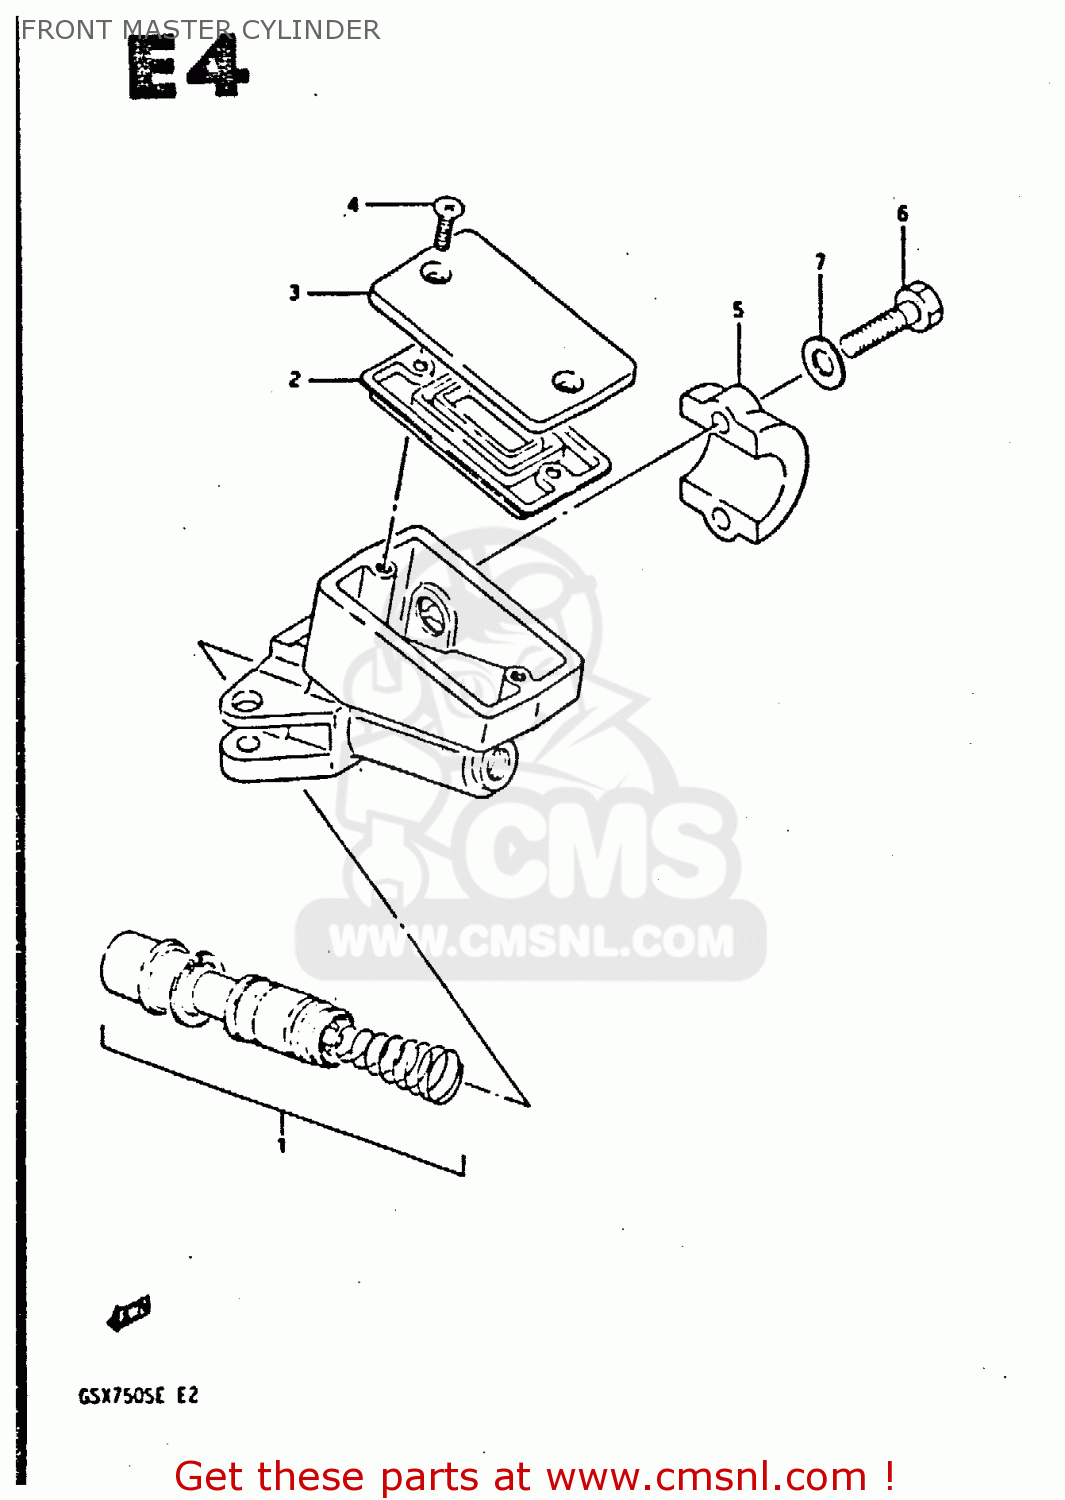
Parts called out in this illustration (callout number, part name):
1	PISTON & CUP SET
2	3
3	CAP
4	SCREW
5	HOLDER,MASTER CYLINDER
6	BOLT
7	WASHER
